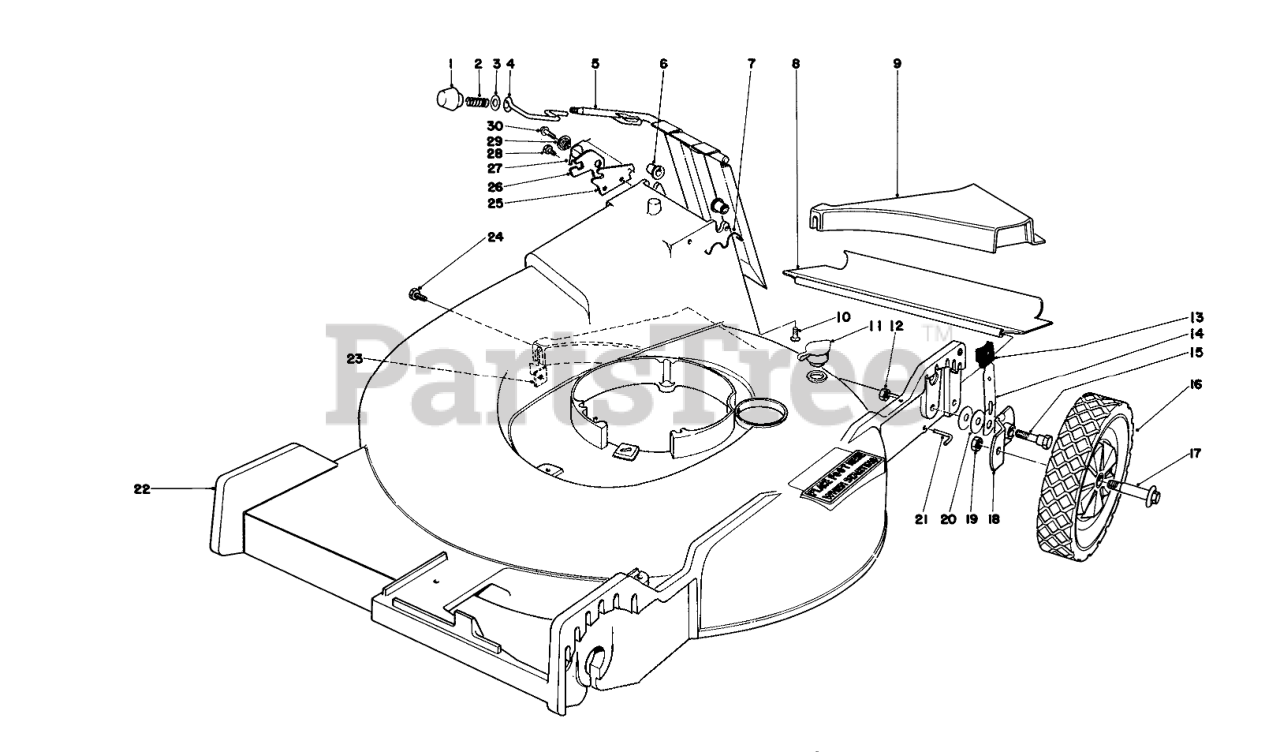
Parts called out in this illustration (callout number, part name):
2	COMPRESSION SPRING
3	WASHER
4	DOOR LATCH
5	Door Handle
6	BUSHING-NYLON
7	Door Retainer
8	REAR SAFETY SHIELD
9	REAR INSERT
10	SCREW-HH
11	WASHOUT PLUG
12	Nut
13	KNOB-ARM
14	SPRING ARM ASM
15	PIVOT SCREW
16	WHEEL TIRE ASM 8 IN
17	BOLT-WHEEL
18	PIVOT ARM ASM A
19	Nut
20	WASHER-PIVOT
21	ROD-SHIELD
22	Housing
23	SPECIAL NUT
24	SCREW THD 1/4 20 5/8
25	DOOR LATCH PLATE
26	Latch Safety
27	TORSION SPRING
28	SCREW-HWH
29	Latch Spacer
30	Screw
